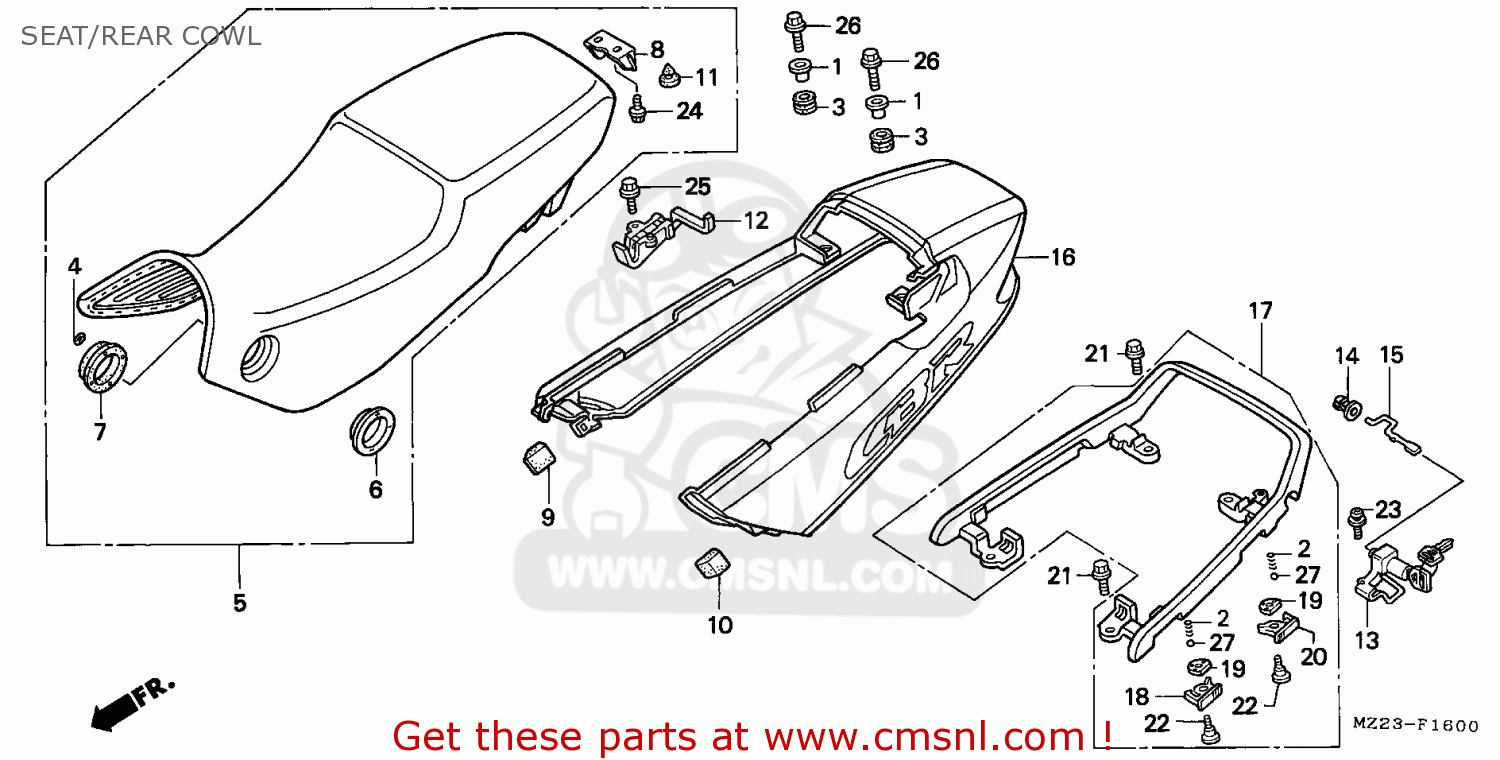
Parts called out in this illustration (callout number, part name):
1	COL,FUEL TANK SET
2	SPRING CLUTCH SUB
3	RUBBER,FR-FEND.MT
4	NUT,SPEED,4MM
5	SEAT ASSY.,*NH1L*
6	GARNISH A
7	GARNISH B
8	BRACKET,SEAT LOCK
9	RUBBER,R.RR.COWL
10	RUBBER,L.RR.COWL
11	RUBBER SET STOP
12	HOOK SEAT CACTH
13	HOLDER ASSY.,HELM
14	HOLDER,ROD
15	BAR,SEAT LOCK
16	SET ILLUS*TYPE16*
17	RAIL ASSY.,R*NH1*
18	HOOK A,LAGGA*NH1*
19	PLATE,HOOK SET
20	HOOK B,LAGGA*NH1*
21	BOLT,SPECIAL,8X18
22	SCREW,PAN,6X22
23	SCREW-WASHER,5X16
25	BOLT,FLANGE,6X20
26	BOLT,FLANGE,SH,6X25
27	BALL,STEEL.,7
